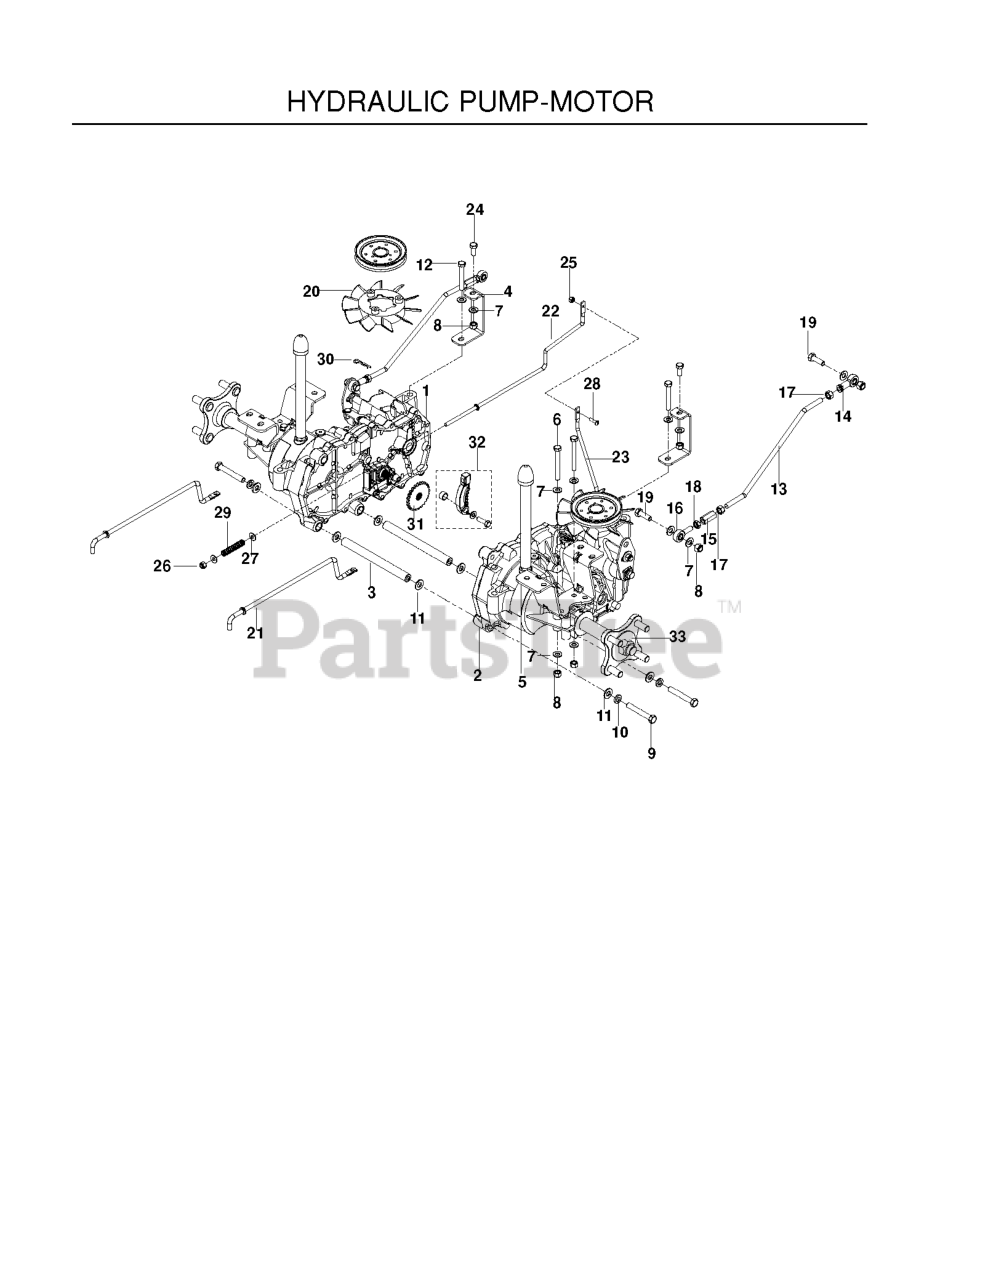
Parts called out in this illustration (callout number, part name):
1	HG_EZT, LT
2	HG_EZT, RT
3	SPACER TUBE, EZT
4	SUPPORT.FRONT.TRANS.BLACK.
5	EZT MOUNT, REAR, BLACK
6	HCS 5/16C X 2-3/4
7	FLAT WASHER 5/16 SAE
8	NUT 5/16 NYLOC
9	HCS 3/8C X 2 1/2
10	SLW 3/8 STD
11	WASHER 3/8 SAE FLAT
13	RP.ROD, MOTION CONTROL
14	RH ROD END
15	ROD END COUPLER
16	RP.ROD.END.LH
18	NUT 5/16F LEFTHAND
19	HCS 5/16C X 1
20	HG_HYDRO FAN 51365
21	LINKAGE, BYPASS, EZT
22	LINKAGE.BRAKE.LT
23	LINKAGE, BRAKE RT
24	HCS 5/16C X 3/4
25	NUT 10-24 NYLOC
26	NUT.1/4-20.HEX.NYLOC.ZD
27	WASHER 1/4 SAE
28	SCR #10-24 X 3/4
30	HAIRPIN #2
31	HG_DISC COG BRAKE 51635
32	HG_KIT BRAKE ARM (EZT)
33	HG_KIT, HYDRO-GEAR HUB
